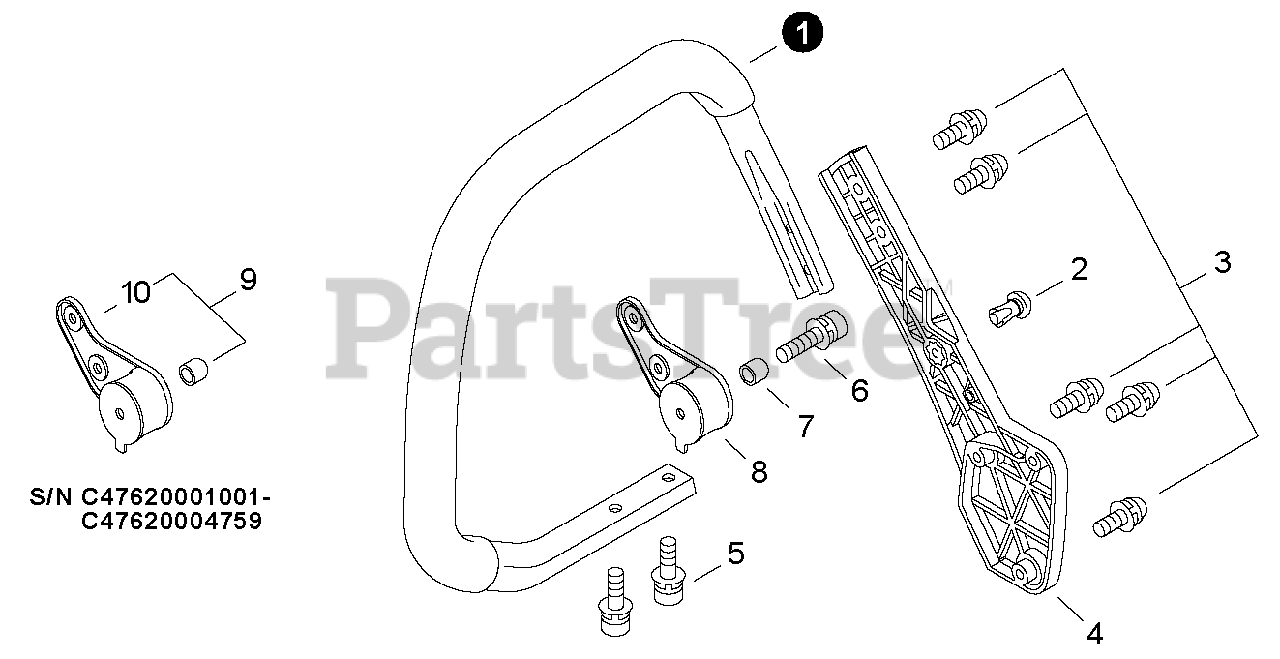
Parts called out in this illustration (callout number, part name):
1	HANDLE - FRONT
3	SCREW - 5X20
4	BRACKET, HANDLE
5	SCREW - 5X14
6	SCREW - 5X20
7	COLLAR - 5
8	CUSHION
9	CUSHION KIT
10	CUSHION
